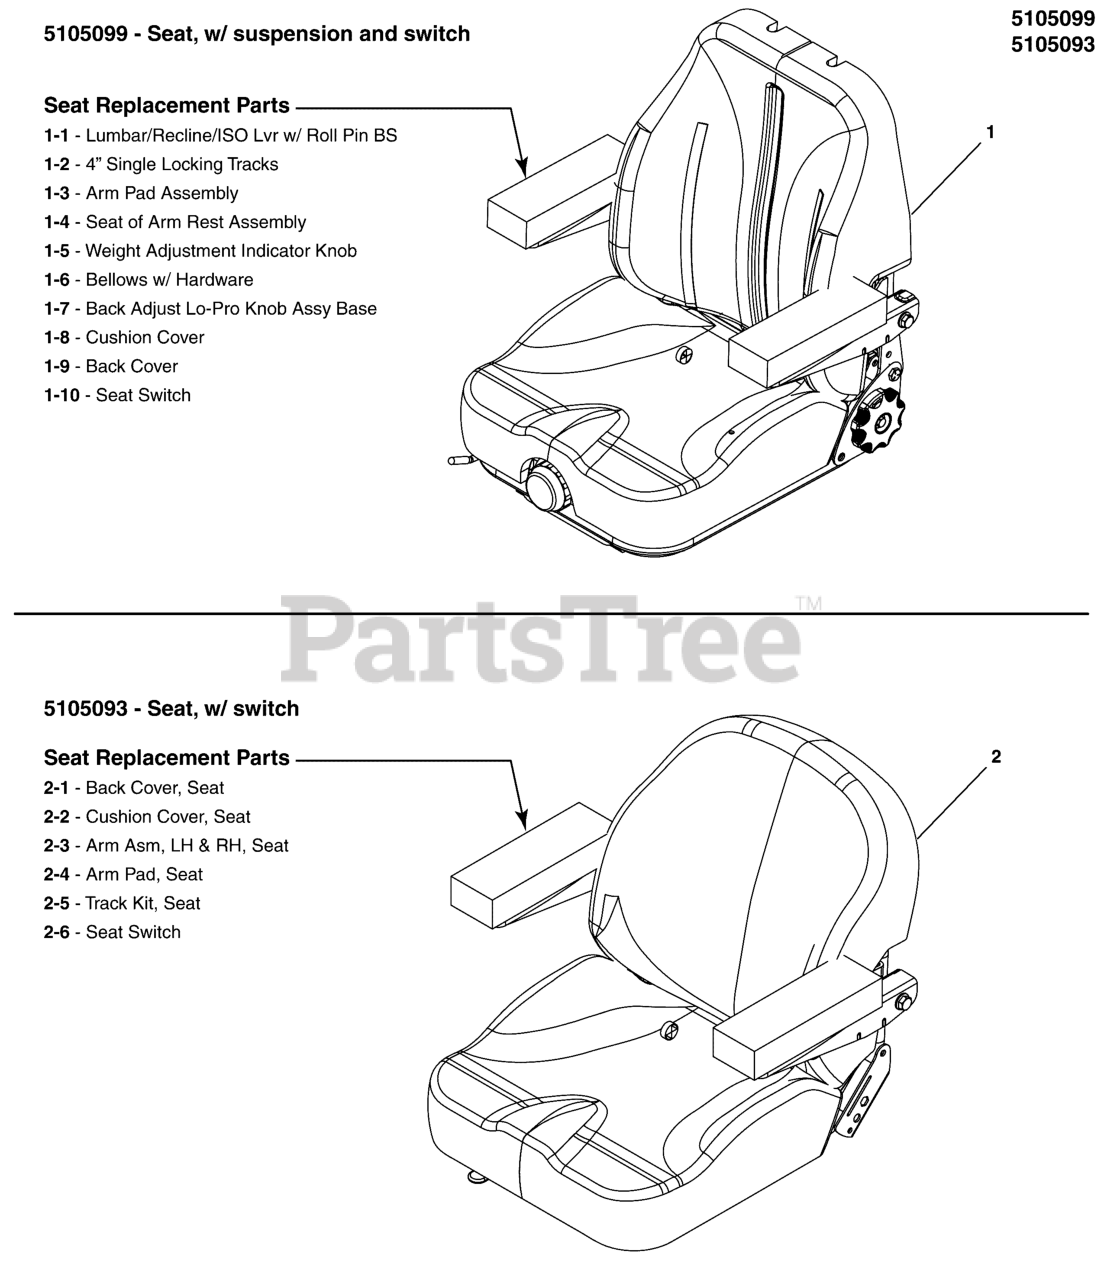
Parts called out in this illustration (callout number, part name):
1	SEAT, HIGH BACK,SEAT'SINC,SUSP, W/SWITCH
1-1	LUMBAR/RECLINE/ISO LVR W/ RLL PIN BS
1-2	4" SINGLE LOCKING TRACKS BASE
1-3	ARM PAD ASSEMBLY BLK/CHAR CAR FIB/HARBR GRY RED WELT
1-4	SET OF ARMREST ASSEMBLY BLK/CHAR CAR FIB/HARBR GRY RED WELT
1-5	WEIGHT ADJUST INDICATOR KNOB ASSY BASE
1-6	BELLOWS W/ HARDWARE BASE
1-7	BACK ADJST LO-PRO KNOB-HRDWR BASE
1-8	CUSHION COVER FOR I3M BLK/CHAR CAR FIB/HARBR GRY RED WELT
1-9	BACK COVER
1-10	SWITCH, SEAT
2	SEAT, C13, SEAT'SINC, 2016, W/SWITCH
2-1	BACK COVER, C13 SEAT
2-2	CUSHION COVER, C13 SEAT
2-3	ARM ASM, lh & RH, C13 SEAT
2-4	ARM PAD, C13 SEAT
2-5	TRACK KIT, C13 SEAT
2-6	SWITCH, SEAT
